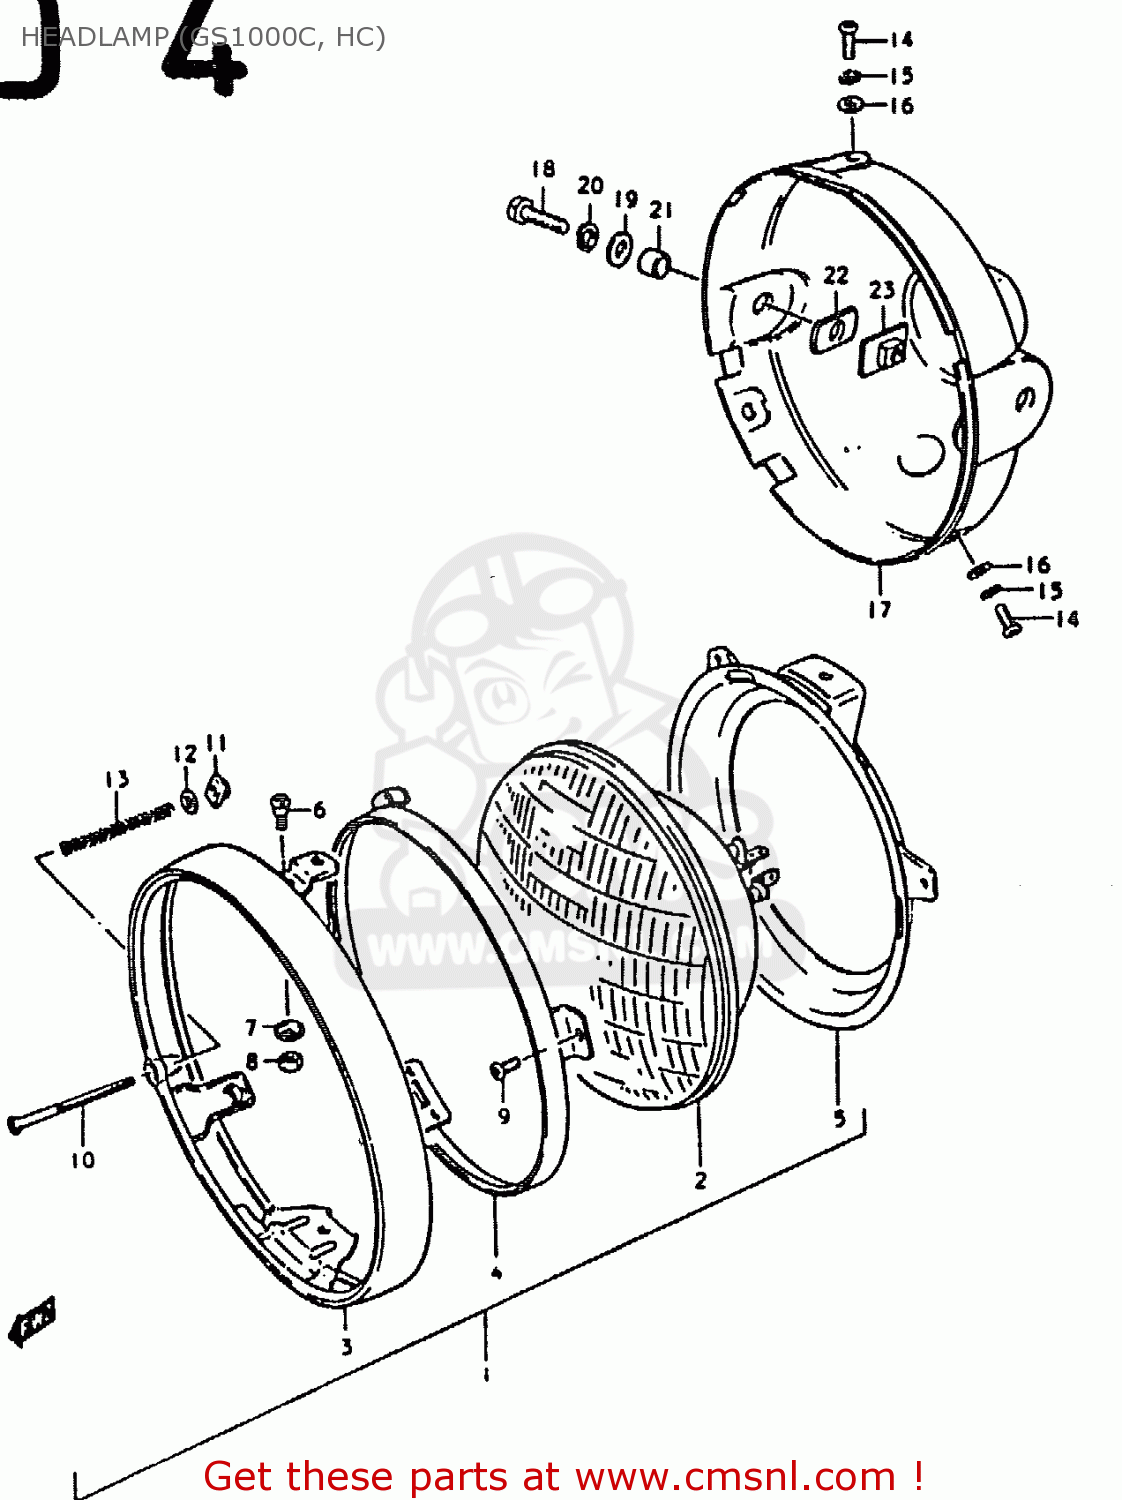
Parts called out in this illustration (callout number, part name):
1	LAMP ASSEMBLY,HEAD
2	LAMP UNIT
3	RIM
4	RETAINER
5	RING,HEADLAMP UNIT
6	SCREW
7	SPACER
8	NUT,ADJUSTING
9	SCREW
10	SCREW,HEADLAMP ADJUST
11	NUT
12	WASHER
13	SPRING,HEADLAMP ADJUST
14	SCREW
15	WASHER,LOCK
16	WASHER
17	HOUSING,HEADLAMP(BLACK)
18	BOLT
19	WASHER
20	LOCK WASHER
21	SPACER (8.8X12X7)
22	CUSHION
23	PLATE,HEADLAMP HOUSING
